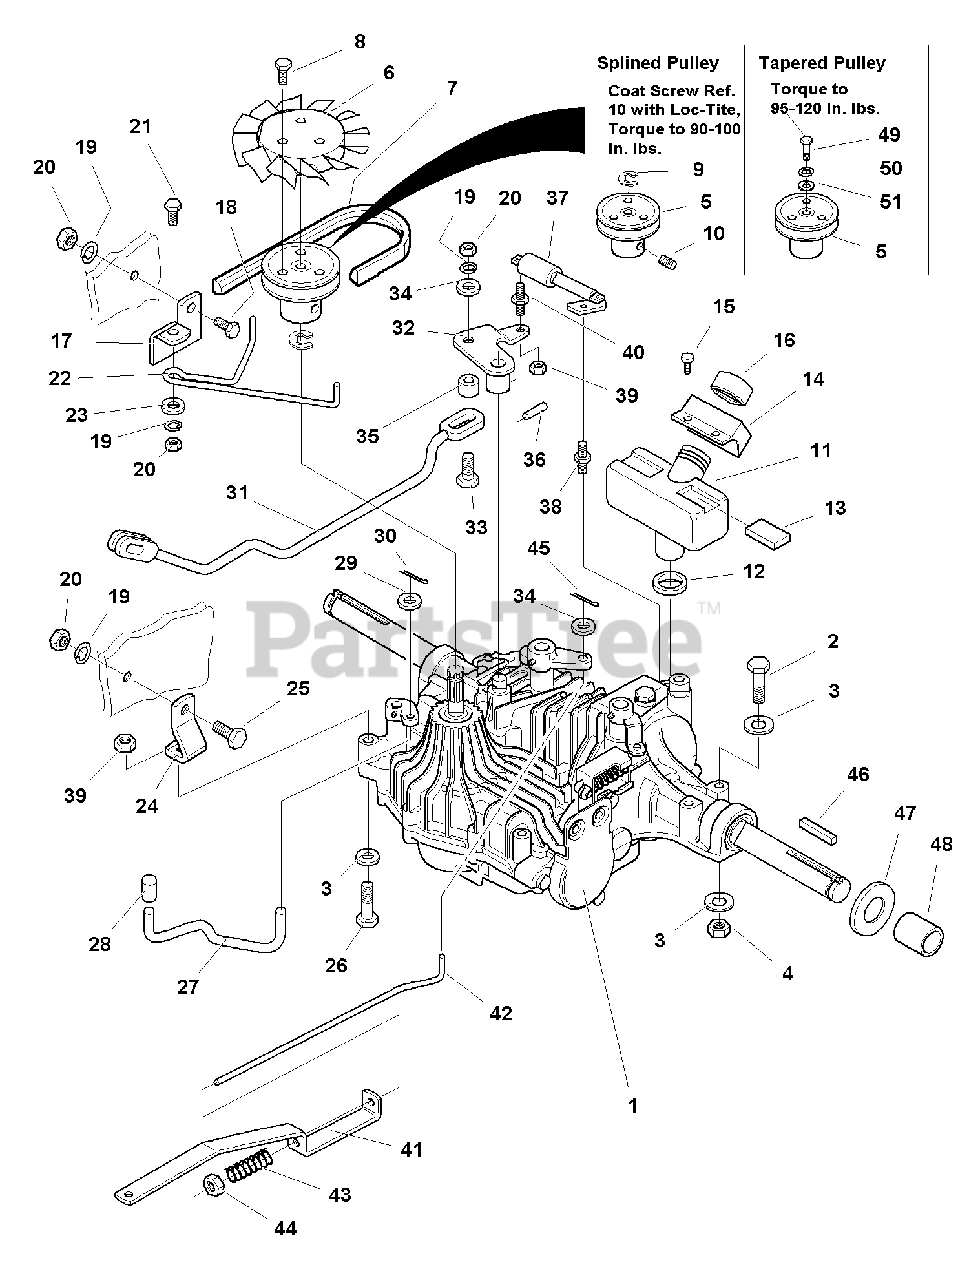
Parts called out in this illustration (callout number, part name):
1	TRANSMISSION, Tuff Torq K61 with Tapered Input Shaft (see Transmission Service Parts - Tuff Torq K61 Transaxle for Service Parts)
2	CAPSCREW, 5/16-18 x 3
3	WASHER, 5/16
4	NUT, Hex Lock, 5/16-18
5	PULLEY & HUB ASSEMBLY (Used with Splined Shaft)
5	PULLEY & HUB ASSEMBLY (Used with Tapered Shaft)
8	CAPSCREW, Taptite, 1/4-20 x 1-1/8
9	RETAINING RING, #55
10	SET SCREW, Hex, 5/16-18 x 5/16
11	TANK, Expansion Chamber
15	FASTENER, Panel
16	CAP, Filler
17	BRACKET, Belt Stop
18	CAPSCREW, Hex Head, 5/16-18 x 1
19	LOCKWASHER, 5/16
20	NUT, Hex, 5/16-18
21	CAPSCREW, Hex Head, 5/16-18 x 1
23	WASHER, Flat, 5/16
24	BRACKET, Torque
25	CAPSCREW, Hex Flange Head, Whizlock, 5/16-18 x 3/4
26	CAPSCREW, 5/16-18 x 2-1/2
27	ROD, Hydro Bypass
29	WASHER, Plain, 1/4
30	COTTER PIN, 1/16 x 3/4
31	ROD, Control
32	CONTROL ARM & HUB ASSEMBLY
33	CAPSCREW, Hex Head, 5/16-18 x 1-1/4
34	WASHER, 5/16
35	SPACER, 21/64 x 9/16 x 5/16
37	SHOCK ABSORBER
39	NUT, Hex Flange Lock, 5/16-18, 2-Way Lock
40	STUD, 5/16-18 x 57/64
41	GUIDE, Brake Rod
43	SPRING, Compression
44	NUT, Hex Nylon Lock, 5/16-18
45	COTTER PIN
46	KEY, 1/4 x 2
48	SPACER, 1-1/64 x 1-3/64 x 1-1/2
49	CAPSCREW, Hex Head, M06 - 1.00 x 30mm
50	LOCKWASHER, 1/4
51	WASHER, 1/4
